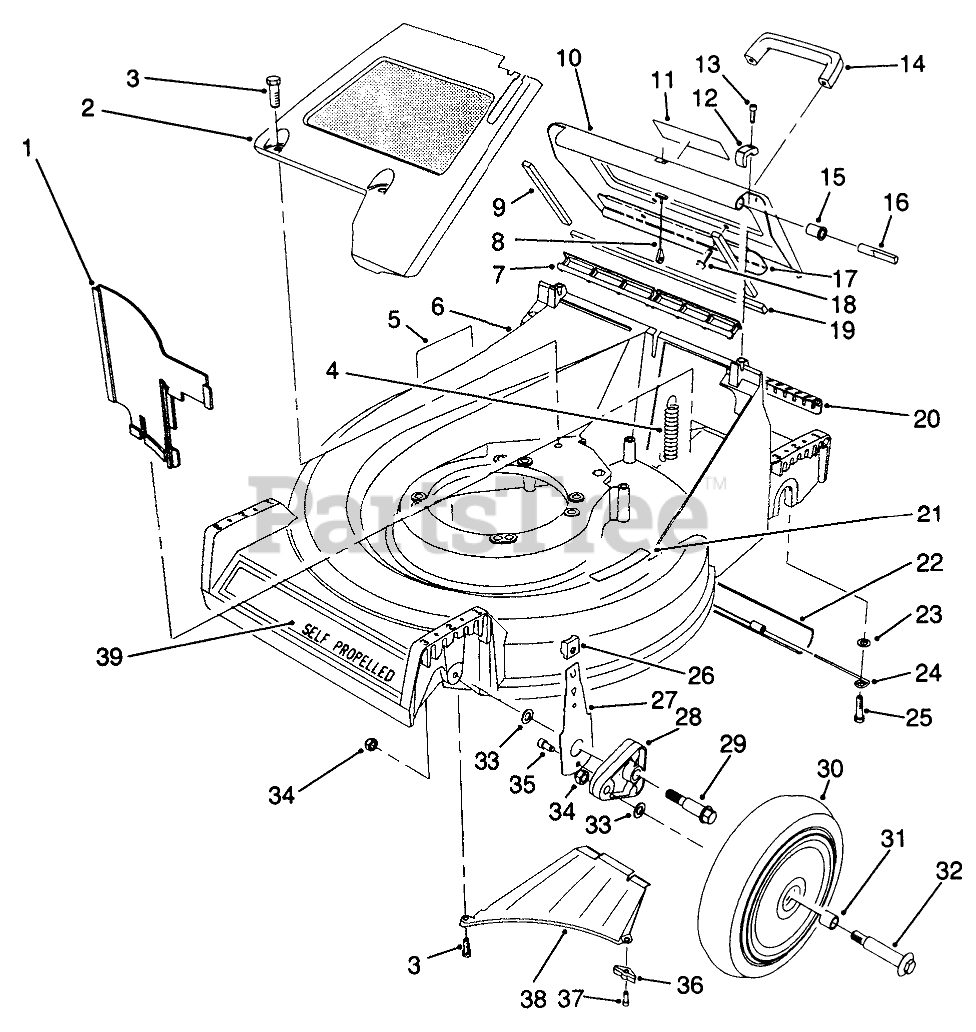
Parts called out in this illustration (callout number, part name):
1	PANEL-VERTICAL
2	PaneI-Screen
3	SCREW-HWHTF
4	EXTENSION-SPRING
5	DECAL-DANGER
6	Housing-21" (Incl. Ref. #5 & 21)
7	DOOR SEAL
8	DOOR CABLE
9	DOOR SIDE SEAL
10	Door-Discharge (Incl. Ref. #9, 11, 17 & 19)
11	DECAL - DANGER
12	HINGE CLAMP
13	SCREW-HSH
14	HANDLE-DOOR
15	DOOR BUSHING
16	HINGE PIN
17	DOOR - BRACE
18	SCREW-HWH
19	DOOR END SEAL
20	ACCESS COVER
21	DECAL - STEP PAD INT'L
22	TRAILING SHIELD
23	WASHER-PLAIN
24	SHIELD HANGER
25	SCREW-SHOULDER
26	KNOB-ARM
27	FRONT SPRING ARM ASM
28	ARM-PIVOT, FRONT
29	BOLT-SHOULDER
30	Wheel & Tire Assembly (Incl. Ref. #31)
31	BUSHING
32	WHEEL BOLT
33	WASHER
34	NUT-LOCK
35	SCREW-HSH, THREAD FORMING
36	Bracket-Discharge
37	SCREW-HWHTF
38	Ramp Discharge
39	DECAL - 53 CM
